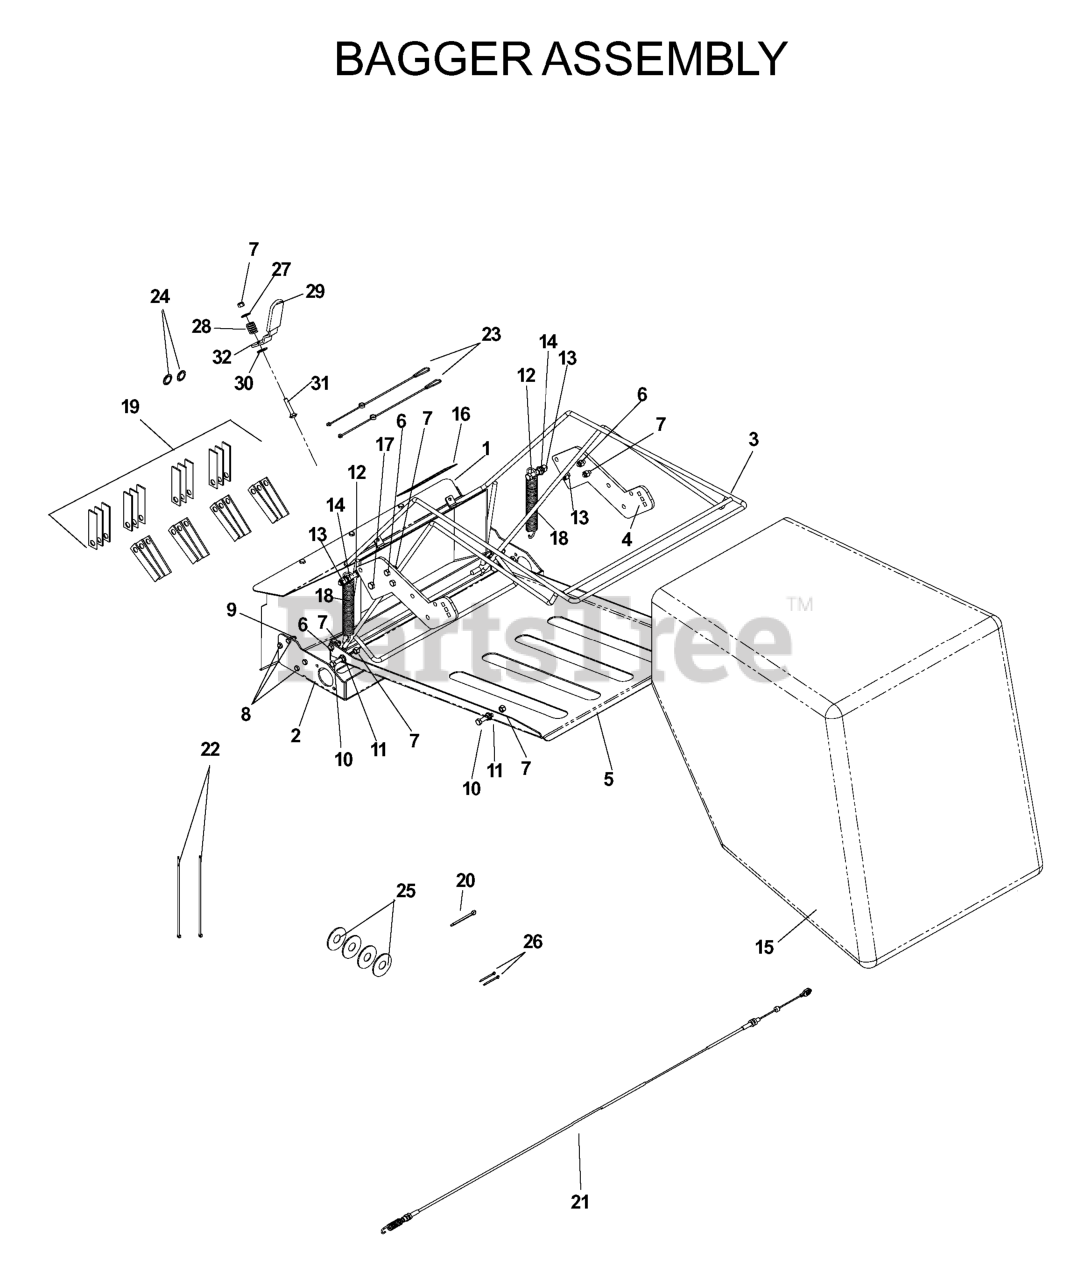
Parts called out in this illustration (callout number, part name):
1	CHUTE
2	BAGGER TRAY
3	BAG FRAME, BLACK
4	EXTENDER GREY
5	SAFETY DOOR ORANGE
6	HCS 5/16C X 1
7	NUT 5/16 NYLOC
8	HCS 1/4C X 3/4 HCS
9	NUT.1/4-20.HEX.NYLOC.ZD
10	HCS 5/16C X 1 3/4
11	NUT 5/16C WHIZ
12	HCS 3/8C X 2
13	NUT 3/8-16 NYLOC
14	NUT 3/8C WHIZ
15	CATCHER BAG
16	DECAL, WARNING
17	HCS 3/8-16X1.GRD.5.ZD
18	SPRING BAGGER
19	BLADE SET, 56 BLADES
20	COTTER PIN
21	CABLE 46.5" POWER RAKE
22	TIE, PLASTIC
24	RETAINING RING
25	WASHER
26	COTTER PIN
27	WASHER 5/16 FLAT
28	COMPRESSION SPRING
30	WASHER 3/8 FLAT
31	RHSNB 5/16-18X1 3/4
